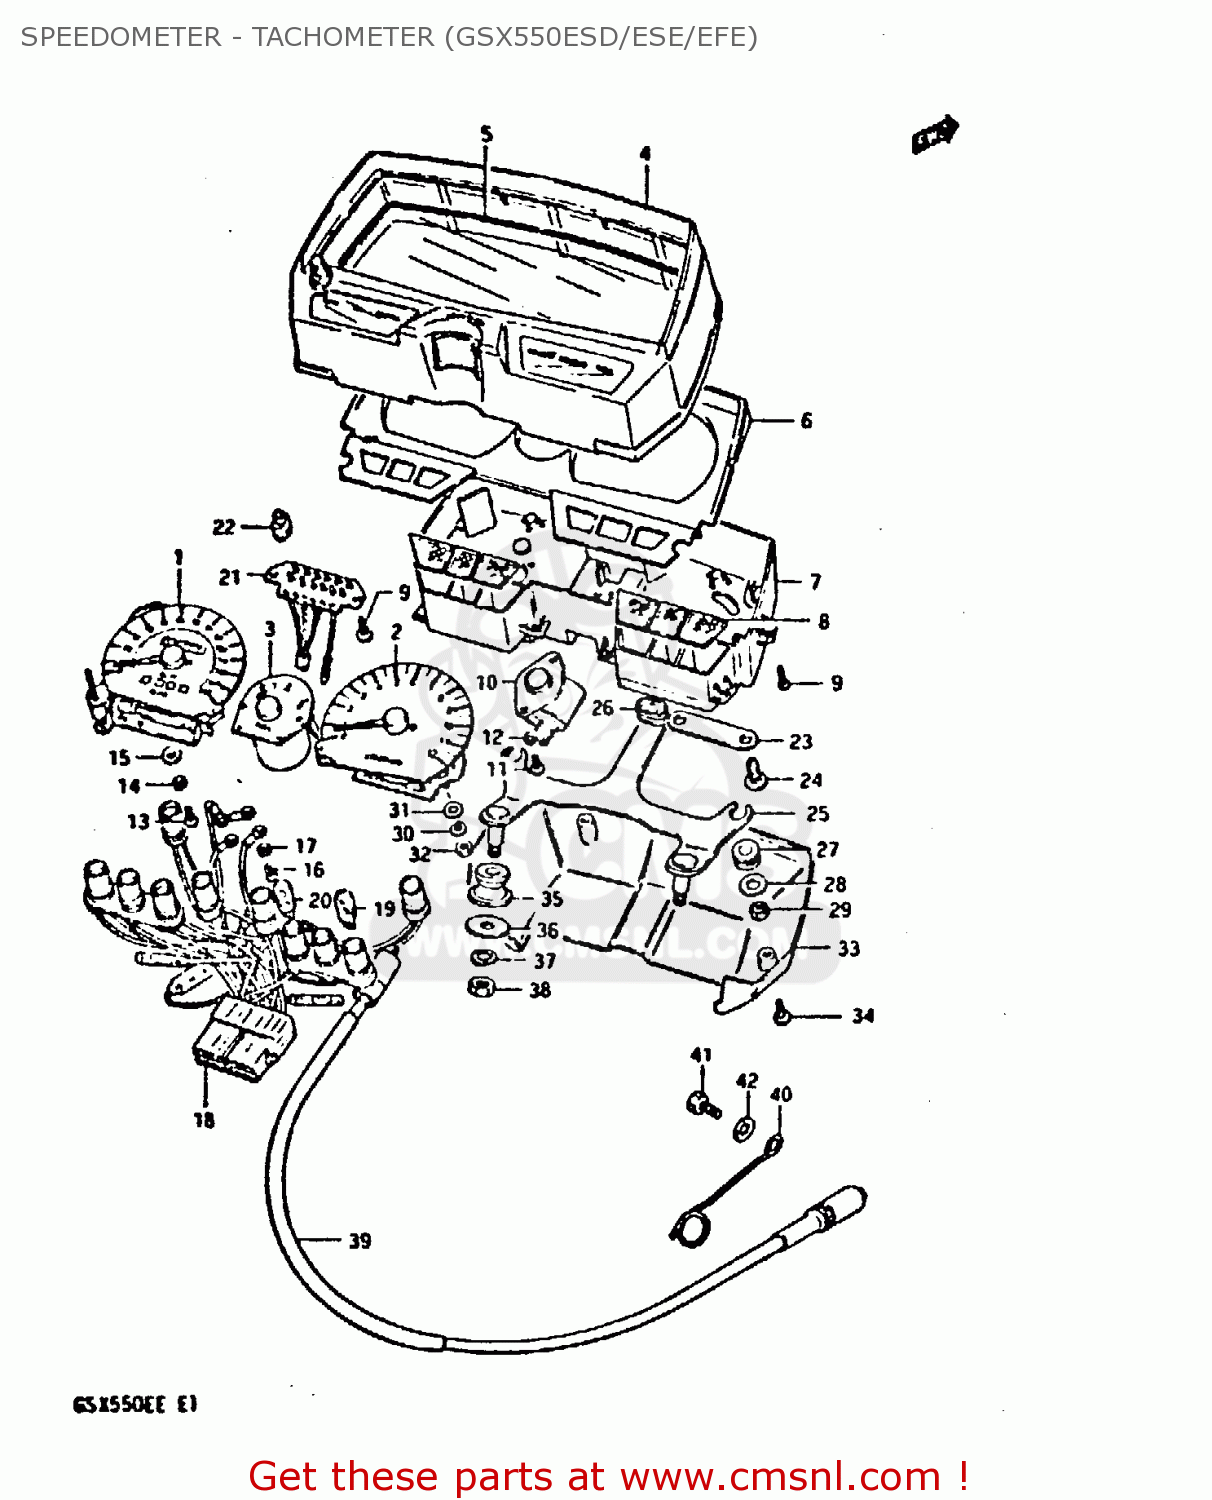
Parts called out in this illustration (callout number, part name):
1	METER,SPEEDOMETER (KM/MPH)
2	TACHOMETER
3	METER,FUEL
4	HOOD,METER
5	GLASS,SPEEDOMETER
6	PLATE,METER WINDOW
7	CASE,METER,INNER
8	LENS SET,PILOT
9	SCREW,GEAR INDICATOR
10	BOX,GEAR
11	SCREW 4X10
12	LOCK WASHER
13	SCREW
14	LOCK WASHER
15	WASHER
16	SCREW
17	WASHER
18	SOCKET,METER
19	BULB(12V3.4W,T10,BF175-01450A)
20	BULB(12V1.7W,T10,WB121)
21	SOCKET,GEAR INDICATOR
22	BULB(14V1.12W)
23	PLATE,COUPLER
24	SCREW
25	BRACKET,METER
26	CUSHION,METER
27	CUSHION,METER
28	WASHER,METER
29	NUT
30	LOCK WASHER
31	WASHER,SPEEDOMETER
32	NUT
33	COVER,METER,UNDER
34	SCREW
35	CUSHION,METER BRACKET
36	WASHER (8.5X20X1.6)
37	LOCK WASHER
38	NUT
39	CABLE ASSEMBLY,SPEEDOMETER
40	CLAMP,SPEEDOMETER CABLE
41	BOLT, UPPER
42	WASHER
